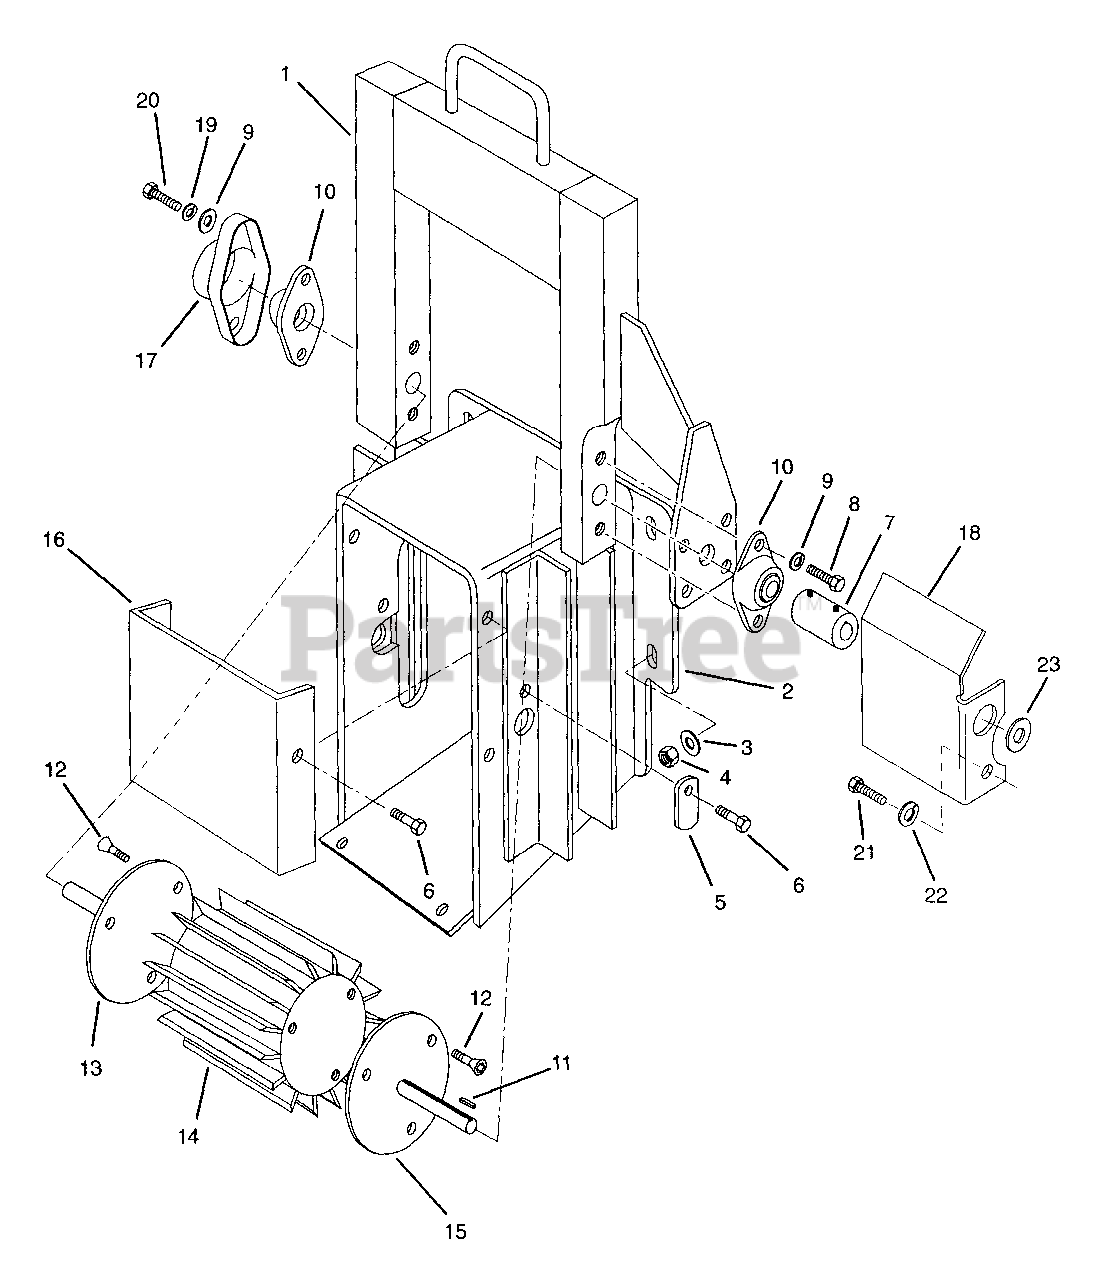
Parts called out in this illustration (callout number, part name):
1	Roller Carrier
2	Frame-Feed Roll
3	Washer-Flat-Steel .406 x 1.00 x .188
4	Nut-Locking Top .38-16
5	Enclosure
6	Screw-Tapping .25-20 x .50-Grade 5
8	Bolt-Hex .44-14 x 1.50-Grade 5
9	Washer-Lock .438 x .133
10	Bearing-Flange
11	Key-Square .25 x .25 x 1.25
12	Bolt -Flat Socket Head .50-13 x 1.0
13	Roller Shaft - Left
15	Roller Shaft - Right
17	Bearing Cover
19	Washer-Flat-Steel .38 x .626 x .033
20	Bolt-Hex .44-14 x 1.25-Grade 5
21	Bolt-Hex .38-16 x 1.00-Grade 5
22	Washer-Lock .38 x .094
23	Washer-Flat-Steel .43 x 1.00 x .083
